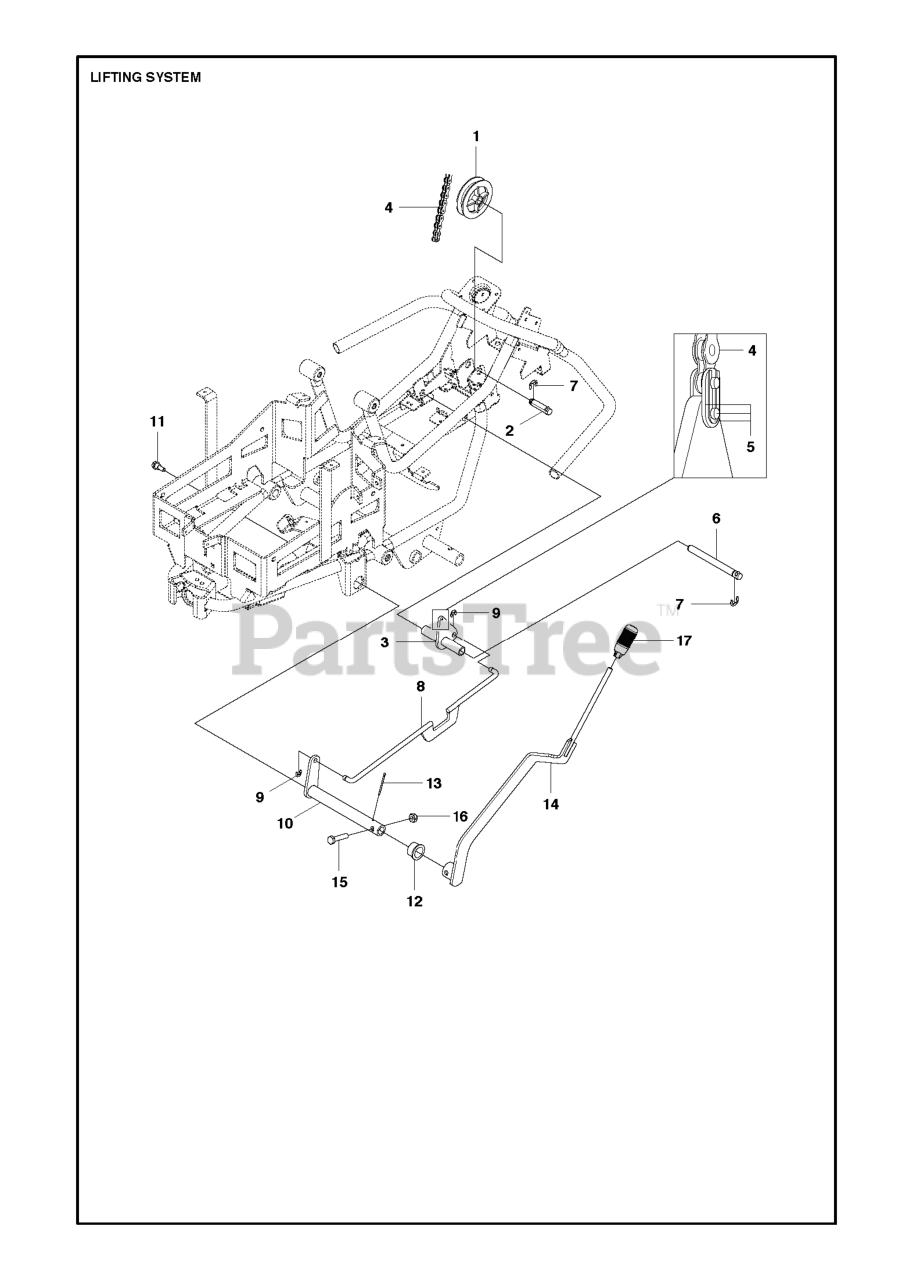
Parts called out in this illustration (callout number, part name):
9	Retaining Ring
12	BEARING FLANGE
13	COTTER PIN
15	REPL BY 725 25 00-71
16	NUT
17	GEAR STICK KNOB
